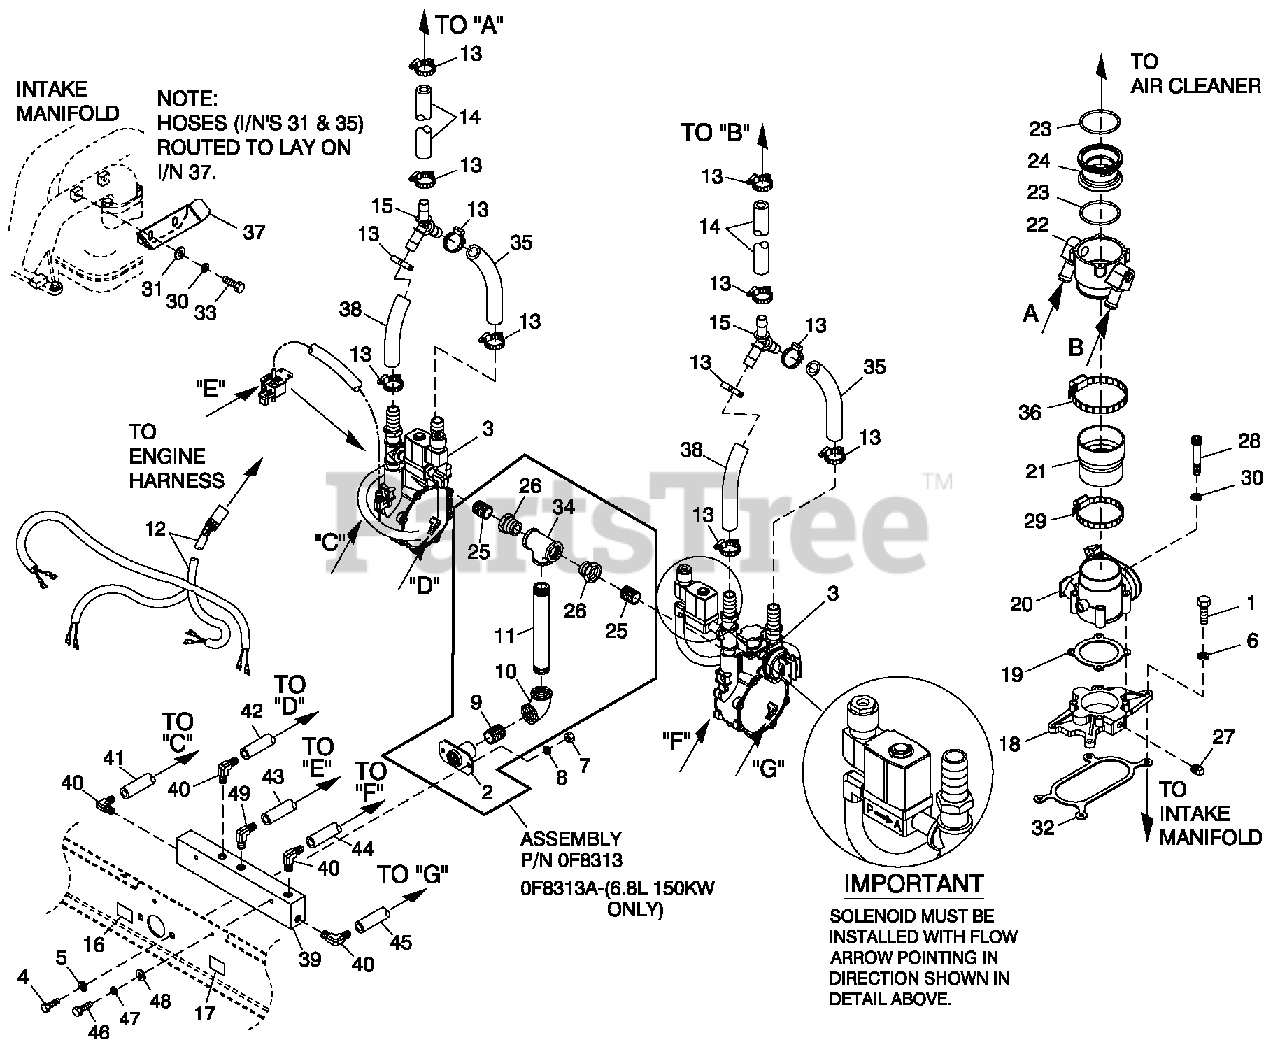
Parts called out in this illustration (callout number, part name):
1	SCREW HHC 5/16-18 X 1-1/4 G5
2	SUPPORT NAT GAS SOLENOID
3	REG 6.8L CPL 130 KW N/G EMISS
4	SCREW HHC M12-1.75 X 20 G8.8
5	WASHER FLAT 1/2 ZINC
6	WASHER LOCK M8-5/16
7	NUT HEX M12-1.75 G8 YEL CHR
8	WASHER LOCK 1/2
9	NIPPLE CLOSE 1.25 NPT X 1.625
10	ELBOW 9 0D 1-1/4 NPT
11	NIPPLE PIPE 1-1/4 NPT X 3 (130 KW)
12	HARNESS, FUEL JUMPER DUAL REG
13	CLAMP HOSE #8 .53-1.00
14	HOSE 3/4 ID SAE-30R2 (42" LG)
15	Y CONNECTOR 500 SERIES BARBS
16	DECAL INLET PRESSURE
17	DECAL FUEL INLET NG
18	ASSY,ADAPTER,THROTTLE BODY
19	GASKET GOVERNOR ACTUATOR
20	ACTUATOR BOSCH 60 GOVERNOR
21	REDUCER 3.0" TO 2.75" TURBO
22	MIXER 40/60MM ACTUATOR ASSY
23	O-RING 2-3/4X3/32X2-15/16
24	VENTURI THROTTLE 44MM (130 KW)
25	NIPPLE CLOSE 3/4X1.375
26	BSHG RDCRHEX1-1/4-3/4
27	PLUG STD PIPE 1/4 STEEL SQ HD
28	SCREW SHC M6-1.0 X 50 C8.8
29	CLAMP HOSE #44 2.31-3.25
30	WASHER LOCK M6-1/4
31	WASHER FLAT M6
32	GASKET ADAPTER THROT BODY
33	SCREW HHC M6-1.0X 20 G8.8
34	PIPE TEE 1-1/4 NPT
35	HOSE 3/4 ID SAE-30R2 (12" LG)
36	CLAMP HOSE #52 2.81-3.75
37	BRACKET, HOSE RISER
38	HOSE 3/4 ID SAE-30R2 (9.5" LG)
39	MANIFOLD, EMISSIONS VACUUM
40	BARBED EL 90 3/16X1/8
41	HOSE VACUUM 5/32 (5"LG)
42	HOSE VACUUM 5/32 (7"LG)
43	HOSE VACUUM 5/32 (18"LG)
44	HOSE VACUUM 5/32 (6"LG)
45	HOSE VACUUM 5/32 (8"LG)
46	SCREW HHC M6-1.0X 25 G8.8
47	WASHER LOCK M6-1/4
48	WASHER FLAT 1/4-M6 ZINC
49	BARBED EL W/VENT (.052")
